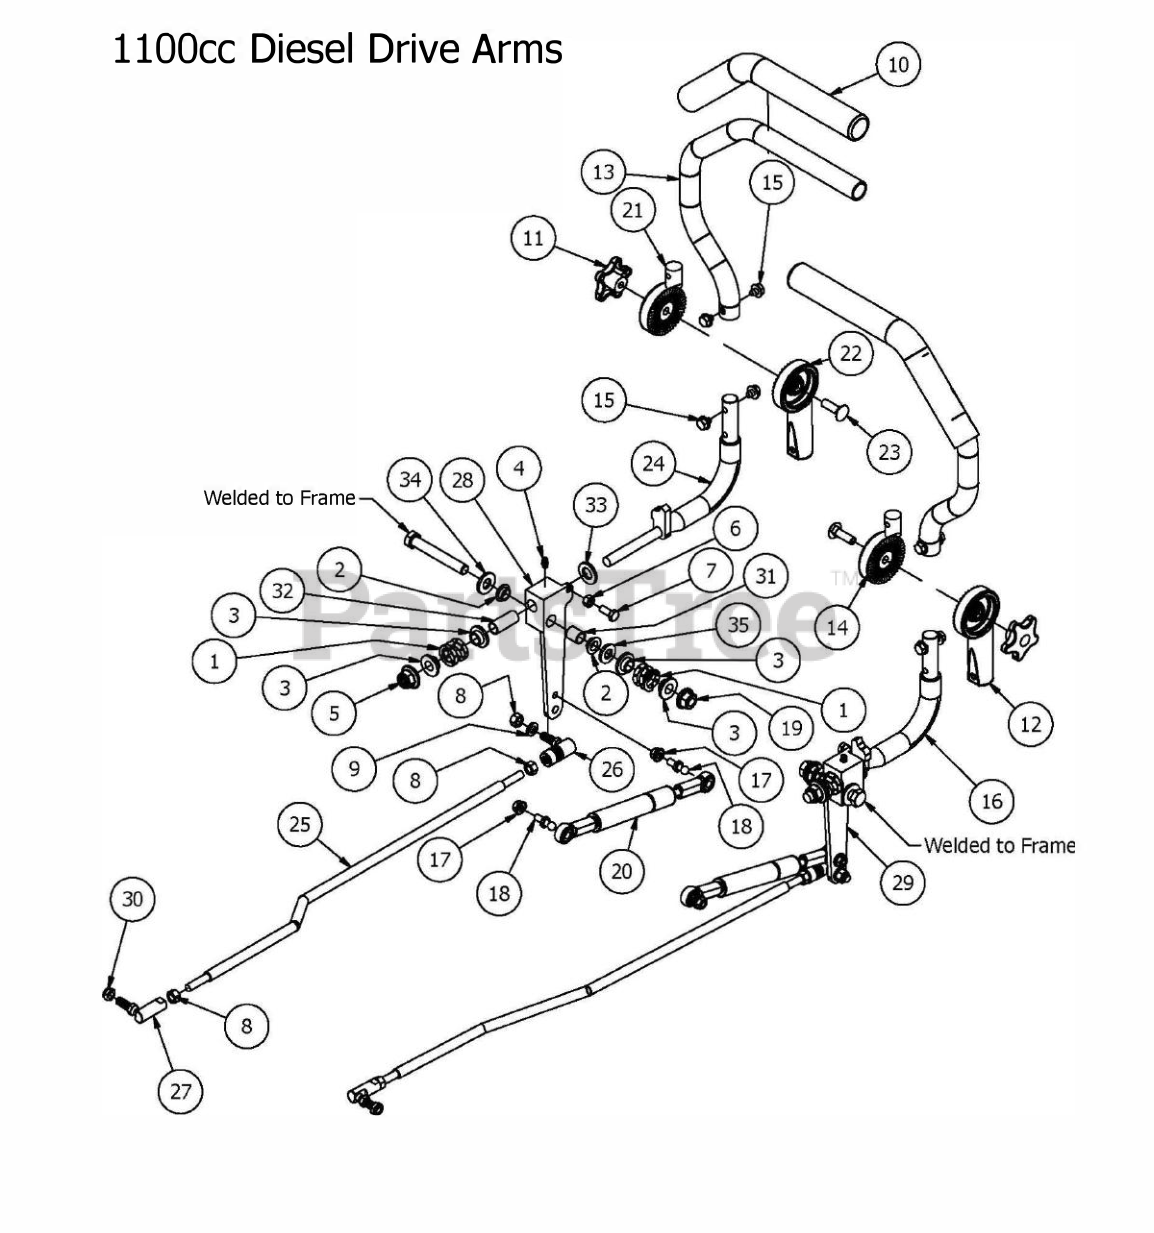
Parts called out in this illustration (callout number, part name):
1	Drive Lever Spring
2	Bushing for 2012 Drive Arms
3	.515 ID Nylon Shoulder Washer
4	1/4" Press in Grease Fitting
5	1/2-13 Nylon Flange Nut
7	5/16" x 3/4" Hex Bolt
8	3/8" Fine Threaded Jam Nut
9	3/8" Lock Washer
10	Black Steering Grip
11	Black Knob for Adjustable Steering Arm
12	Lower Adjuster -Steering Arm- Right
13	Upper Tube-Adjustable Steering
14	Upper Adjust Steering Arm- Right
15	5/16-18 1/2 HWH Bolt-Steering
16	Steering Arm Elbow - Right
17	5/16" Flange Nut
18	10mm Damper Ball Stud-Steering
19	1/2-13 Hex Flange (GR.G) ZC
20	Steering Damper
21	Upper adjuster-Steering Arm- Left
22	Lower Adjuster - Steering Arm- Left
23	3/8" x 1 1/4" Carriage Bolt
24	Steering Arm Elbow - Right
25	1100cc Diesel Push Rod
26	Quick Release Ball Joint
27	3/8-24 Ball Joint
28	Drive Arm Lever Housing (Left)
29	Drive Arm Lever Housing Right
30	3/8-24 Nylon Insert jam locknut
31	Drive Arm Block Insert-short
32	Drive Arm Block Insert-long
33	.630 ID Plastic Washer
34	.505 Nylon Spacer
35	.505x1x .125 Oil Impregnated washer
